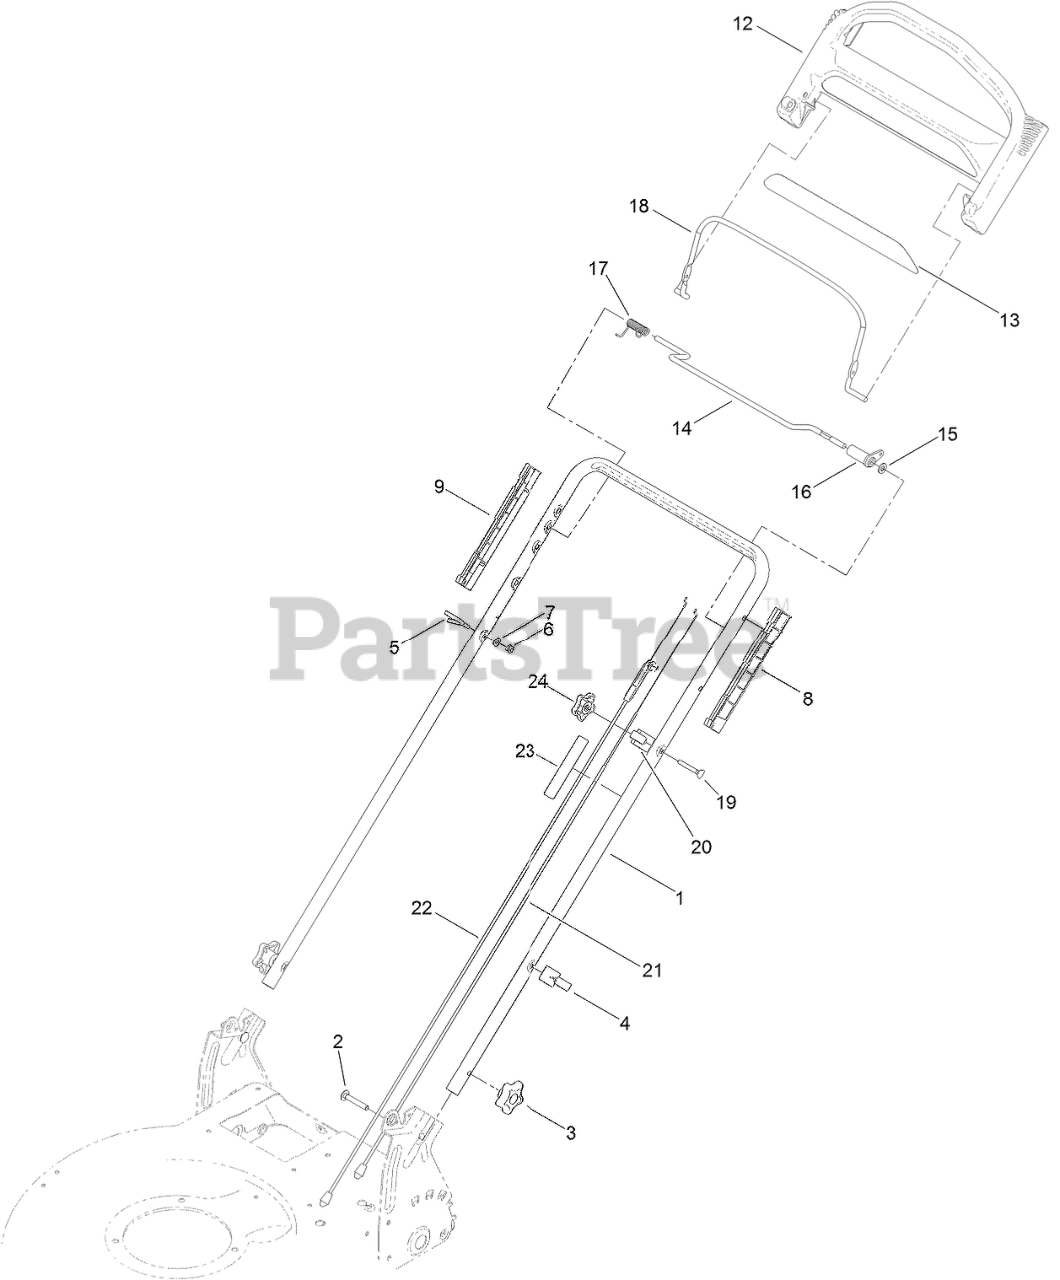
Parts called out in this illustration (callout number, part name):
2	Screw-CARR
3	KNOB-HANDLE
4	GUIDE-CABLE
5	GUIDE-ROPE
6	NUT-LOCK, NI
7	WASHER-FLAT
8	GUIDE-LH
9	GUIDE-RH
12	HANDLE-CONTROL
13	DECAL-HANDLE
14	BAR-CONTROL, TRACTION
15	WASHER-PLAIN
16	LEVER-TRACTION
17	Spring-Torsion
18	Bail-Brake
19	SCREW
20	ANCHOR-CABLE
21	CABLE-TRACTION
22	CABLE-BRAKE
23	DECAL-TRACTION, ADJUST
24	KNOB-HANDLE, LOCKING
